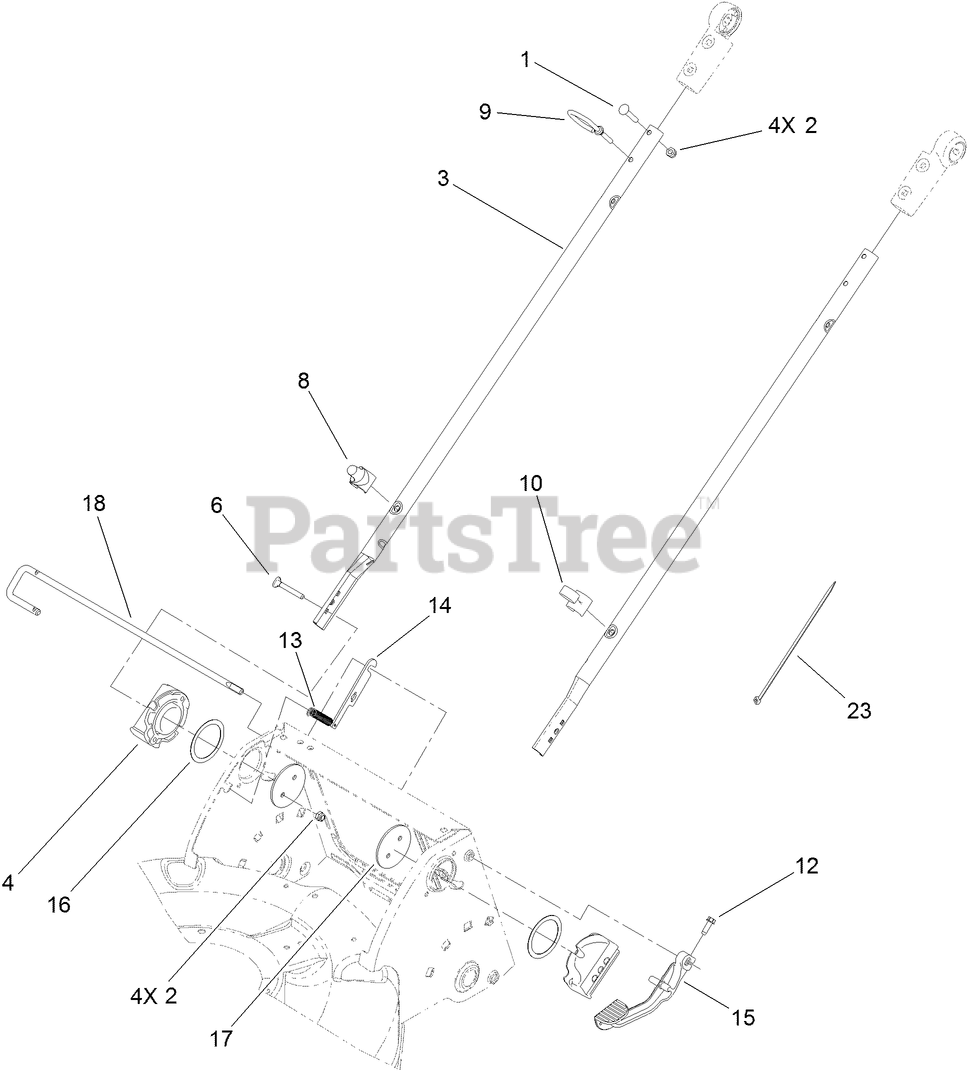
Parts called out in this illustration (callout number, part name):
1	SCREW-CARR
2	NUT-LOCK, NI
4	MOUNT-HANDLE
9	GUIDE-ROPE, UPPER
10	GUIDE-CABLE
12	SCREW-HWHTF
13	SPRING-EXTENSION
14	PLATE-ROD, RELEASE
15	LEVER-RELEASE
16	WASHER-NYLON
18	ROD-RELEASE, HANDLE
23	TIE-CABLE
